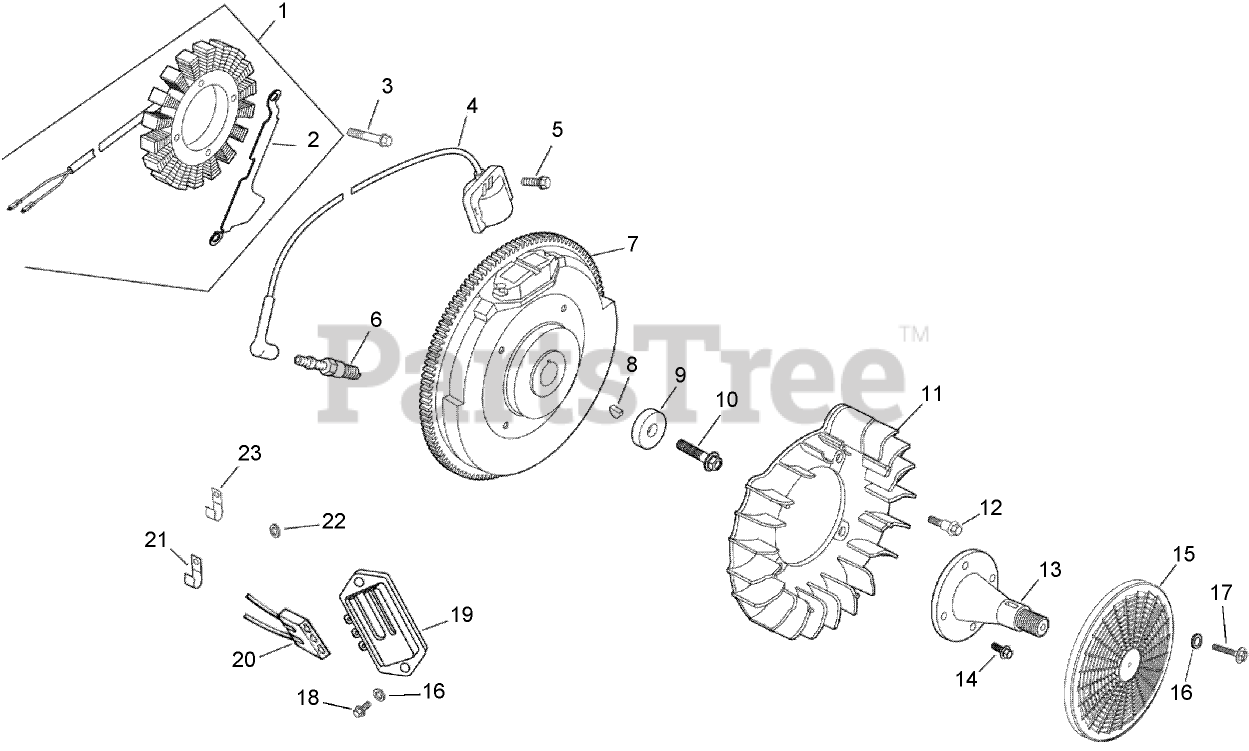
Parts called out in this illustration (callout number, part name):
1	Stator Kit (Includes 2)
2	Bracket-Wire, Stator
3	SCREW-THREAD FORMING (M5X0.8X25)
4	Module-Ignition
5	SCREW-FLANGE, THREAD FORMING (M5X.8X20)
6	Spark Plug
7	Flywheel
8	KEY (3/16 X 5/8)
9	WASHER-FLAT (13/32)
10	SCREW-FLANGE (M10X1.5X45)
11	Fan
12	BOLT-SHOULDER (M6x1.0x16)
13	Shaft-Drive, Front
14	Screw-HF (M8x1.25x25)
15	Screen-Grass
16	WASHER-FLAT (.188)
17	SCREW-FLANGE, SEMS (M4X.7X25)
18	SCREW-PHL HD (11-16X.88)
19	Rectifier-Regulator
20	Connector (3 contact)
21	Clip-Cable
22	WASHER-FLAT (1/4)
23	CLIP-CABLE
